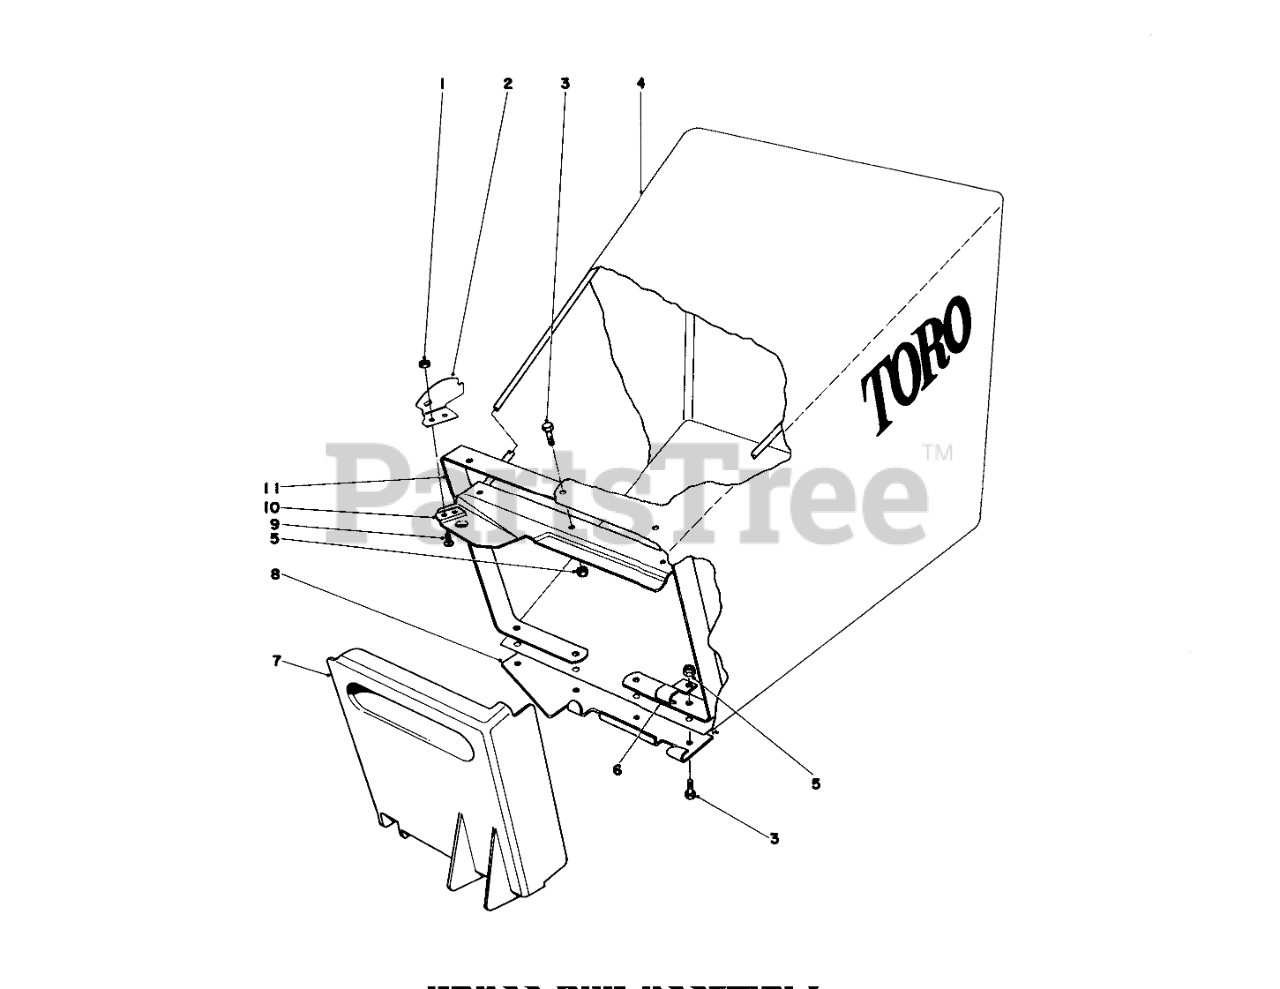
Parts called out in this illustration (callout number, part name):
1	NUT-LOCK
2	Latch Bag
3	SCREW-HWH
4	REPLACMNT BAG 44-0530
5	NUT-LOCK, SIDE
6	SUPPORT BRACKET
7	BAG DOOR
8	DOOR BRACKET
9	Screw
10	Bag Frame
11	LOWER BAG FRAME
